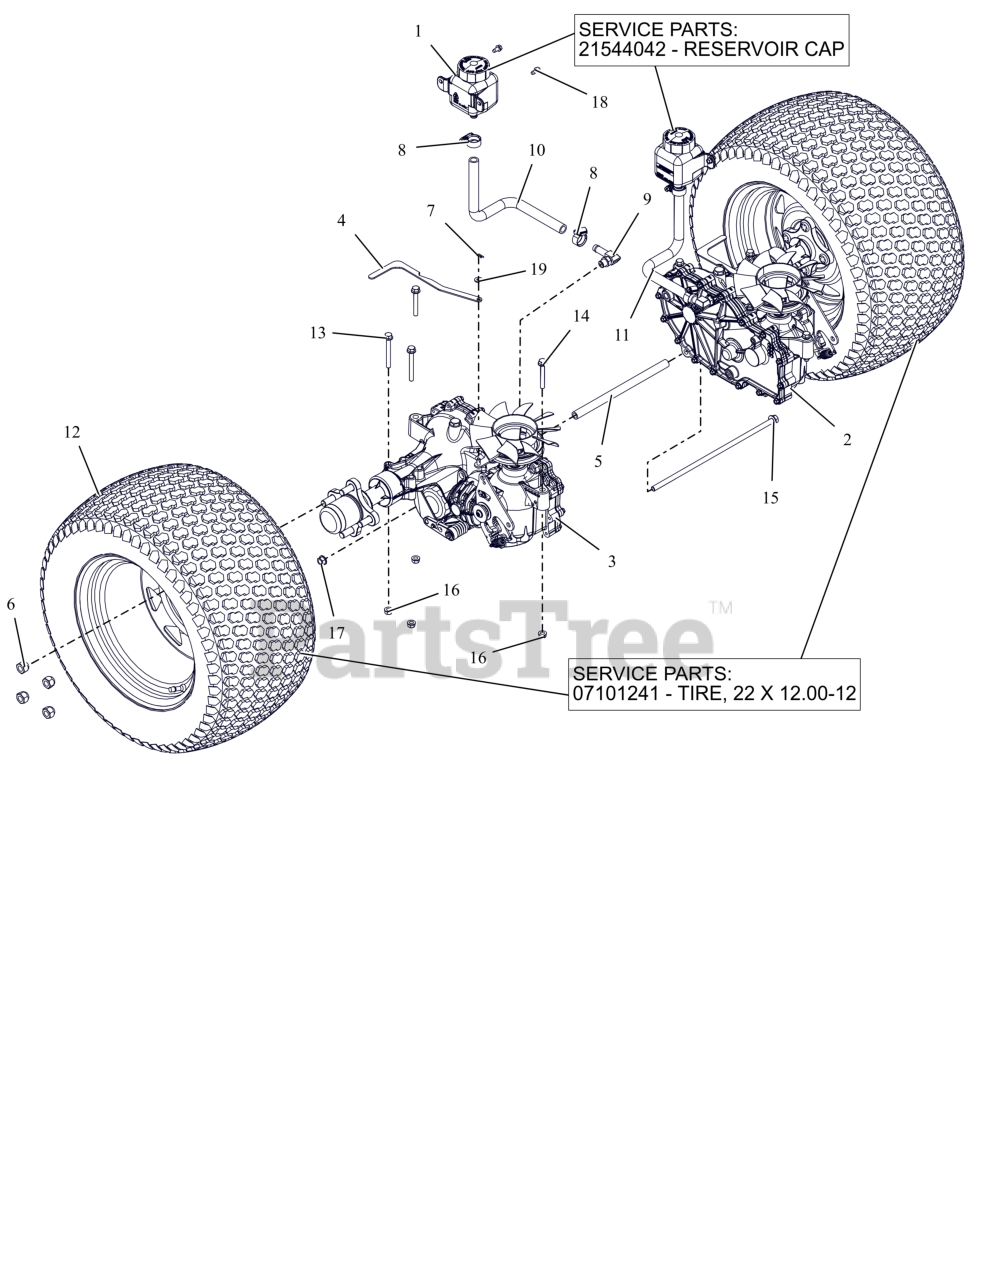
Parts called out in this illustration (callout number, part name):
1	TANK, EXPANSION
1	CAP, HYDRO RESERVOIR REPLAC.
2	TRANSAXLE, ZT3100 LH
3	TRANSAXLE, ZT3100 RH
4	BRKT, VALVE DUMP
5	SPCR,TRANS. .406IDX.63ODX9.95L
6	NUT, WHEEL .50-20 ZCC
7	PIN, HAIR #225 .072X1.09
8	CLAMP,.88 DIA. HOSE
9	FITTING, HYD (90 DEG)
10	HOSE, FORMED EXPANSION -HD RH
11	HOSE, FORMED EXPANSION -HD LH
12	ASM, WHL/TIRE 22X12.00-12 K500
12	TIRE, 22X12.00-12
13	BLT,HEX-FLG .31-18X2.75 G5 ZCC
14	BLT,HEX-FLG .31-18X2.25 G5 ZCC
15	BLT,HEX-FLG .38-16X13 G5 ZCC
16	NUT,LK-CTR-FLG .31-18 GF ZCC
17	NUT-LK-CTR-FLG .375-16 GF ZCC
18	SCR-TAP .25-20X.50 HWH ZCC
19	WSHR,FLT .281X.625X.065 ZCC
